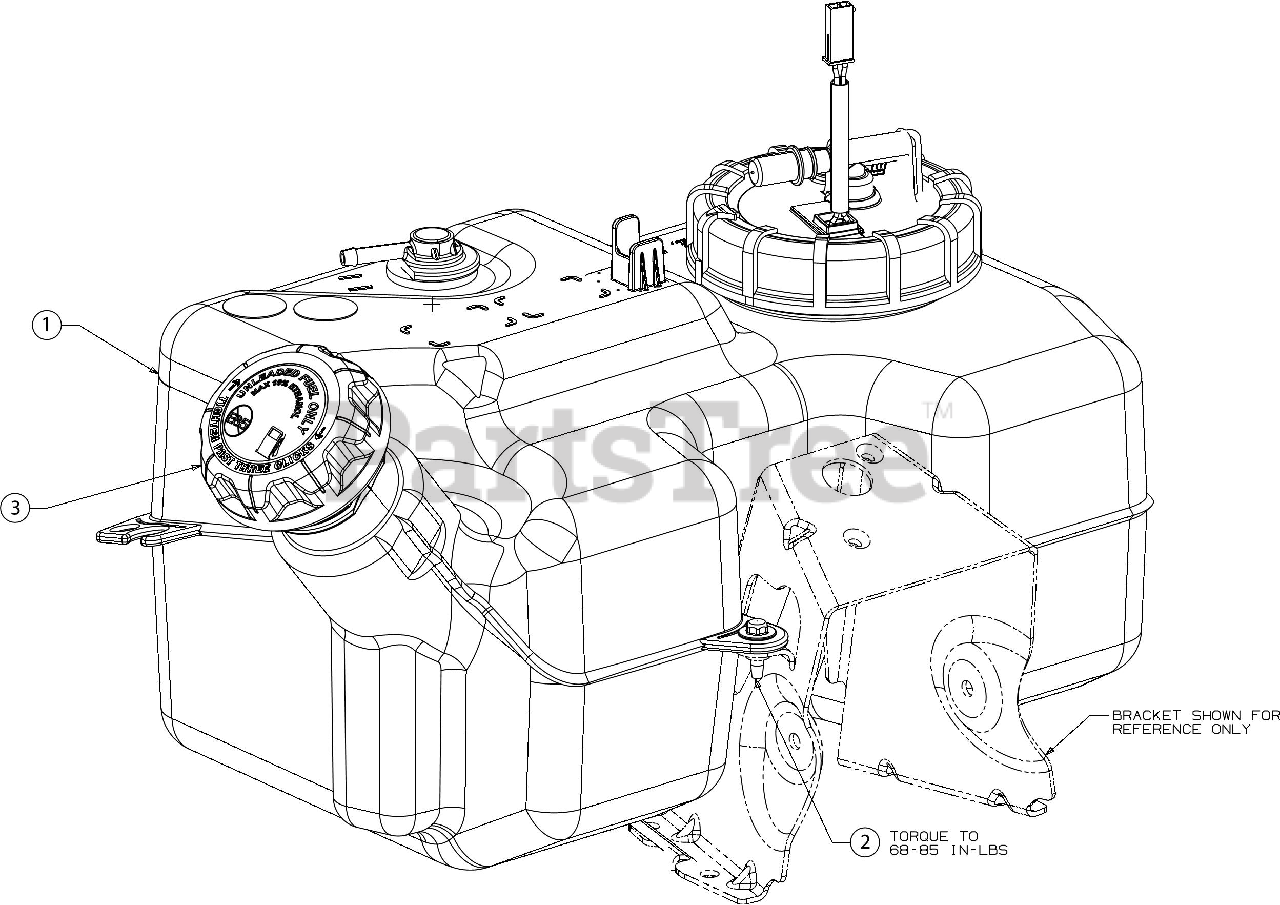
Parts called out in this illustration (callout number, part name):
1	EFI FUEL TANK ASSEMBLY 2.5 GAL
2	SHOULDER SCREW M6-1 .368 X.115
3	FUEL CAP W/TETHER
